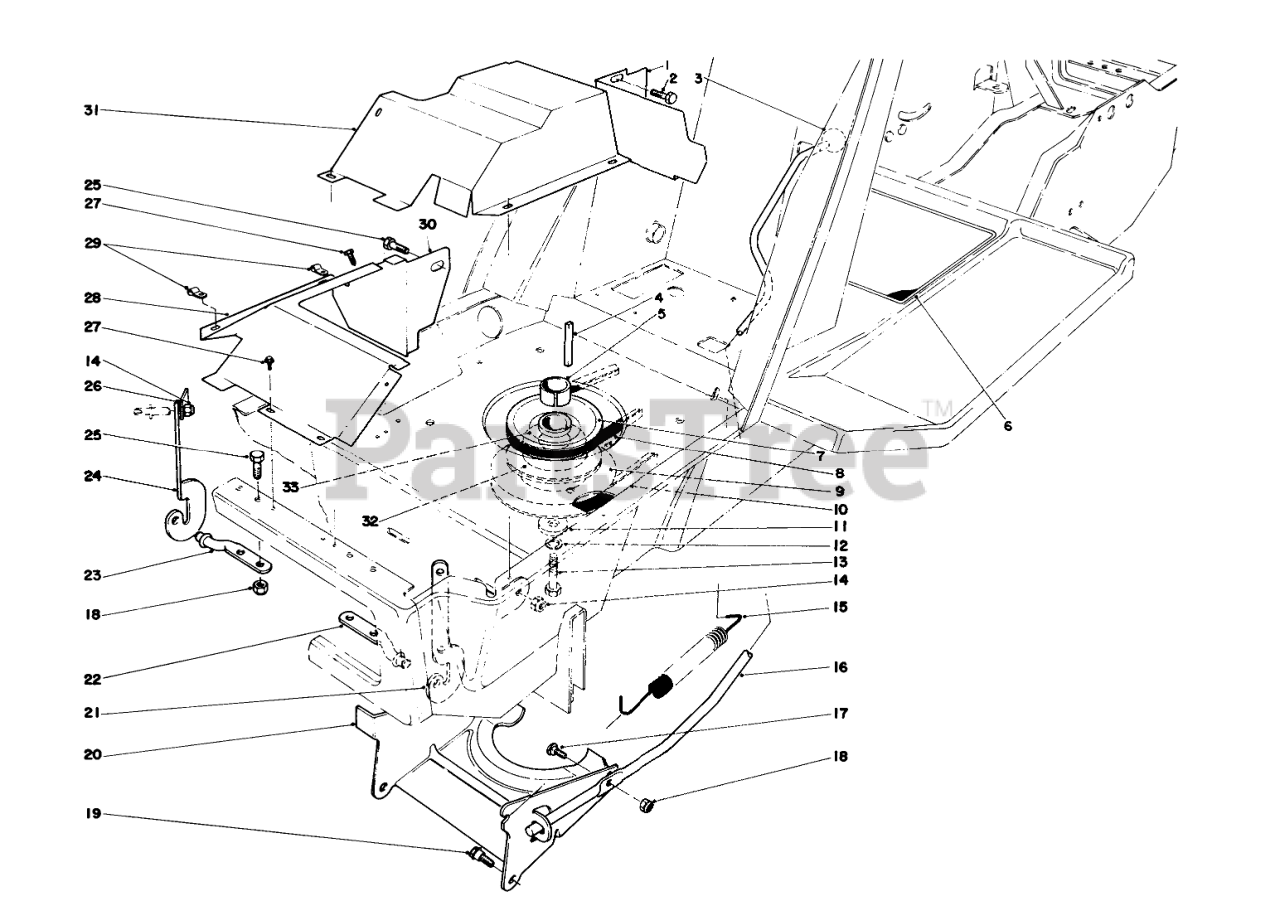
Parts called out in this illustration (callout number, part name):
1	EXH SHIELD SUPT B
2	SCREW-HH
4	KEY-SQUARE
5	PULLEY SPACER
6	OPERATION DECAL
7	TOP SHEAVE
8	V BELT
9	Clutch & Brake-Deck (Incl. Ref. #32 & 33)
10	V BELT
11	WASHER
12	WASHER-LOCK
13	SCREW-HH
14	NUT-LOCK, CONE
15	TRACTION SPRING
16	Engagement Lever
17	Bolt
18	NUT-LOCK, CONE
19	SCREW-SHOULDER
20	Actuator-Clutch
21	L.H. HINGE BRACKET
22	LH HOOD HINGE PIN
23	RH HOOD HINGE PIN
24	RH HINGE BRKT
25	SCREW-HH
26	SCREEN SUPT BRKT
27	SCREW-HWHTF
28	Heat Shield
29	CABLE CLAMP
30	Support Heat Shield
31	HEAT SHIELD WA B
32	CLUTCH PLATTER
33	SPRING WASHER
